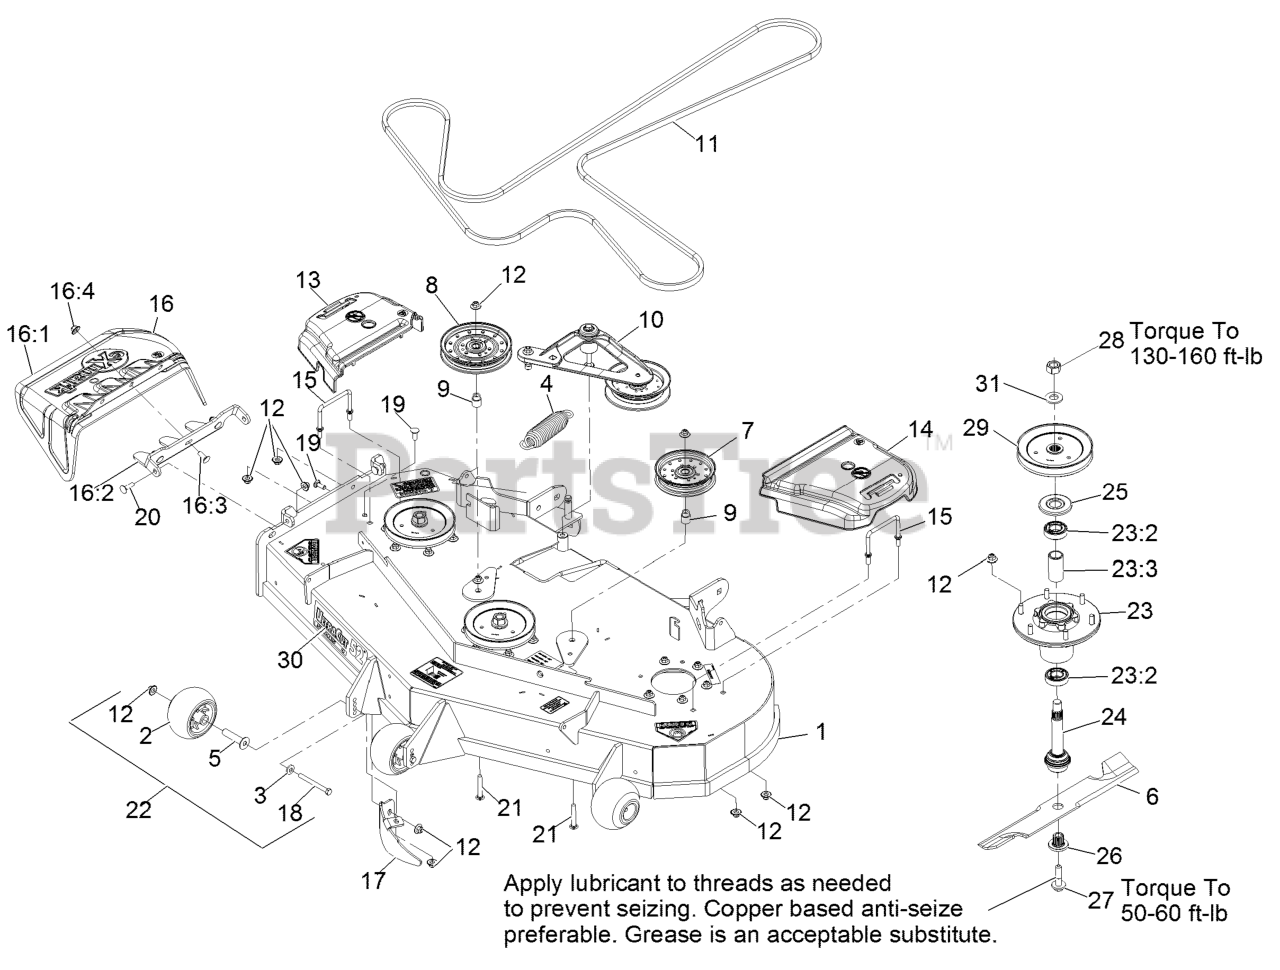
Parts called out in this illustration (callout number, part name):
1	ASM,DECK W/ DECALS 52
2	ROLLER-SCALP, ANTI
3	WASHER-BELLEVILLE
4	SPRING-EXTENSION
5	AXLE, ROLLER
9	BUSHING-IDLER
10	DECK IDLER ASM
11	BELT,V-B X 186.00"
12	Nut-Nyloc 3/8-16 Flg
13	COVER-BELT, RH
14	COVER-BELT, LH
15	WIREFORM-COVER
16	ASM,DISCHARGE CHUTE
16:1	CHUTE,DISCHARGE
16:2	BRACKET,DISCHARGE CHUTE
16:3	SCREW-CARR
16:4	Nut-Nyloc 3/8-16 Flg
17	BAFFLE-DOGLEG, LZ-VT52
18	SCREW-HH 3/8-16 X 3 3/4 GR 8
19	SCREW-CARR
20	Bolt-Carriage 3/8-16 X 1 1/4
21	SCREW-CARR
22	KIT, ANTI-SCALP ROLLER
23	ASM-CUTTER HSG WITH BEARINGS
23:2	BEARING-BALL
23:3	SPACER-BEARING
24	ASM-SPINDLE AND SEAL
25	GUARD,BEARING TOP .989
26	BUSHING,SPLINED
27	SCREW,SEMS 1/2-20 X 2.19
28	NUT-HEX
29	SHEAVE,BLADE DRIVE 6.50
30	DECAL,ULTRACUT 52 SERIES
